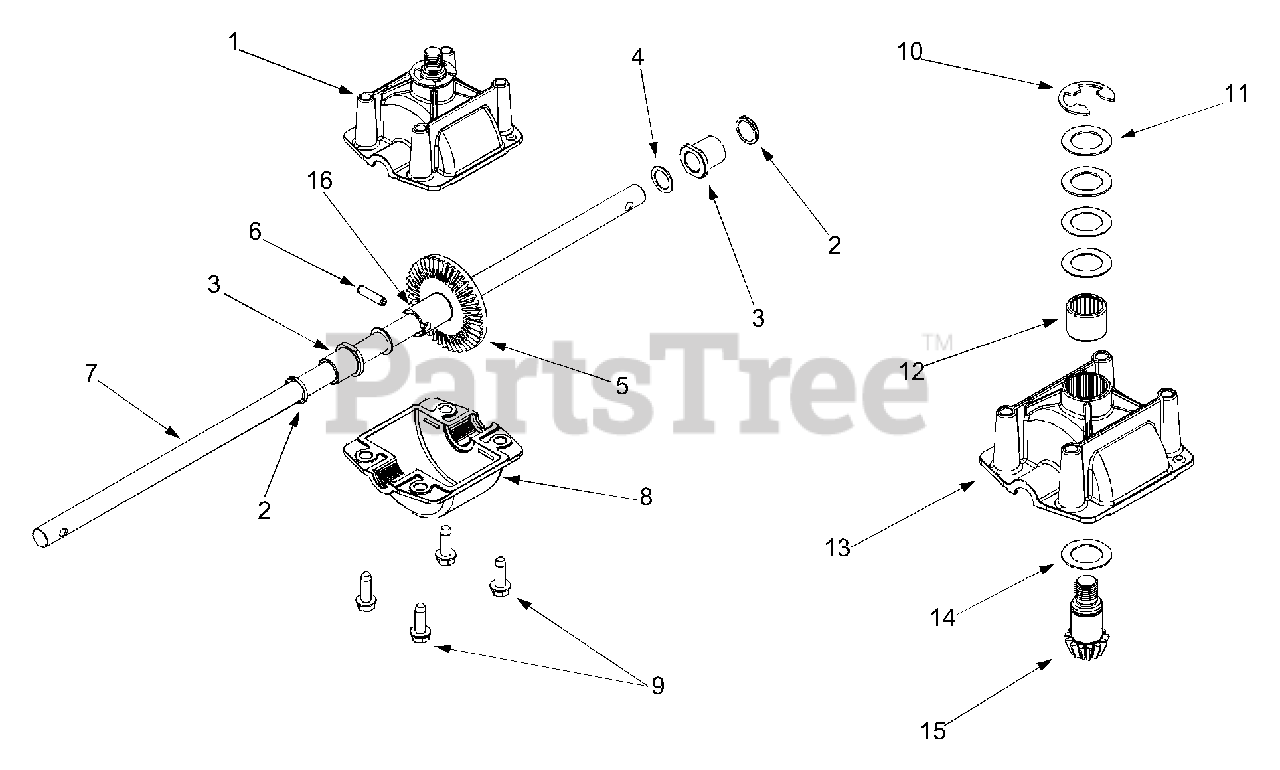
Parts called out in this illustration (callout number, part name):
1	Upper Housing Assembly
2	Oil Seal.500 ID x.687 OD
3	Flange Bearing.503 ID x.689 OD
4	Flat Washer.504 ID x.700 OD x.030
5	Bevel Gear 44T
6	Roll Pin
7	Output Shaft
8	Lower Housing
9	Hex Washer Screw 1/4-20 x.75
10	E-Ring.750
11	Flat Washer.625 ID x 1.0 OD x.030
12	Needle Bearing.625 x.813
13	Upper Housing
14	Flat Washer.625 ID x 1.0 OD x.030
15	Input Shaft
16	Spacer.505 x.75 x.9765
